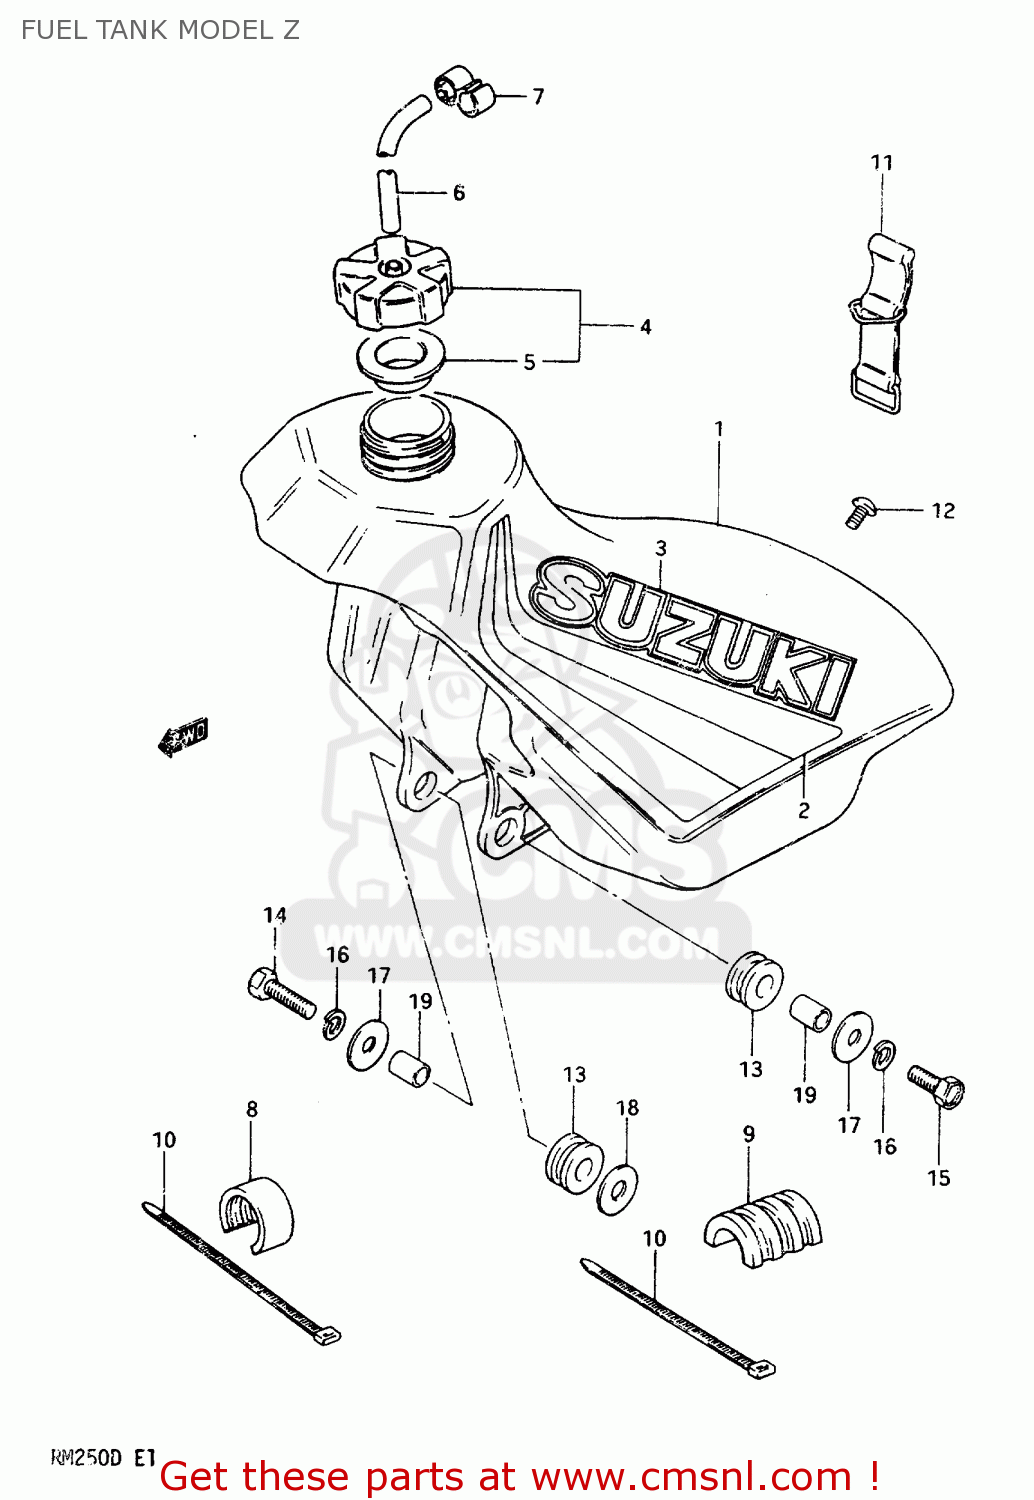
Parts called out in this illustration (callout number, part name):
1	TANK ASSEMBLY,FUEL
2	TAPE SET,FUEL TANK
3	EMBLEM
4	CAP SET,FUEL TANK
5	GASKET,FUEL TANK CAP (NAS)
6	HOSE
7	CLAMP,BREATHER HOSE
8	CUSHION,FUEL TANK UPR FR
9	CUSHION,FUEL TANK,UPPER
10	CLAMP
11	BAND
12	SCREW (6X15)
13	CUSHION
14	BOLT 8X45
15	BOLT
16	LOCK WASHER
17	WASHER
18	WASHER(8.5X26X1.2)
19	SPACER (8.8X12X13.5)
